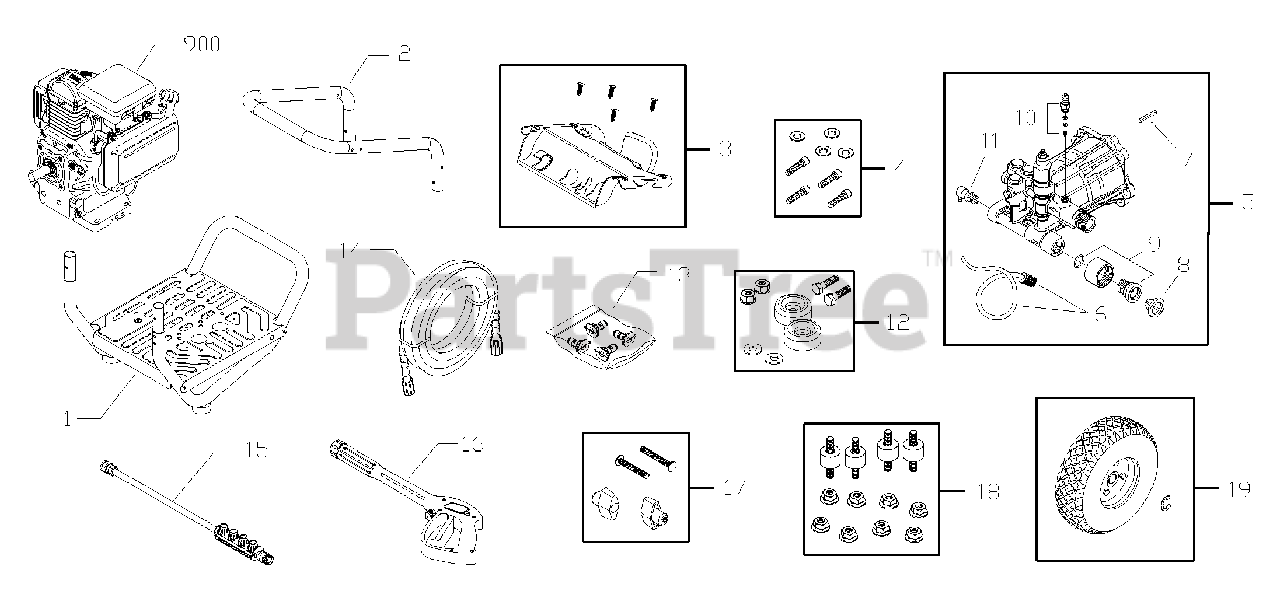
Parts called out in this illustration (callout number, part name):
4	KIT, Hardware, Pump Mounting
5	PUMP
6	KIT, Chemical Hose
9	KIT, Water Inlet
10	KIT, Chemical Injection
11	VALVE, Thermal Relief
12	KIT, Vibration Mount
13	KIT, QC Nozzles
14	HOSE, 25’
15	EXTENSION, QC
16	GUN
17	KIT, Hardware, Handle
18	KIT, Vibration Mount
900	*ENGINE
